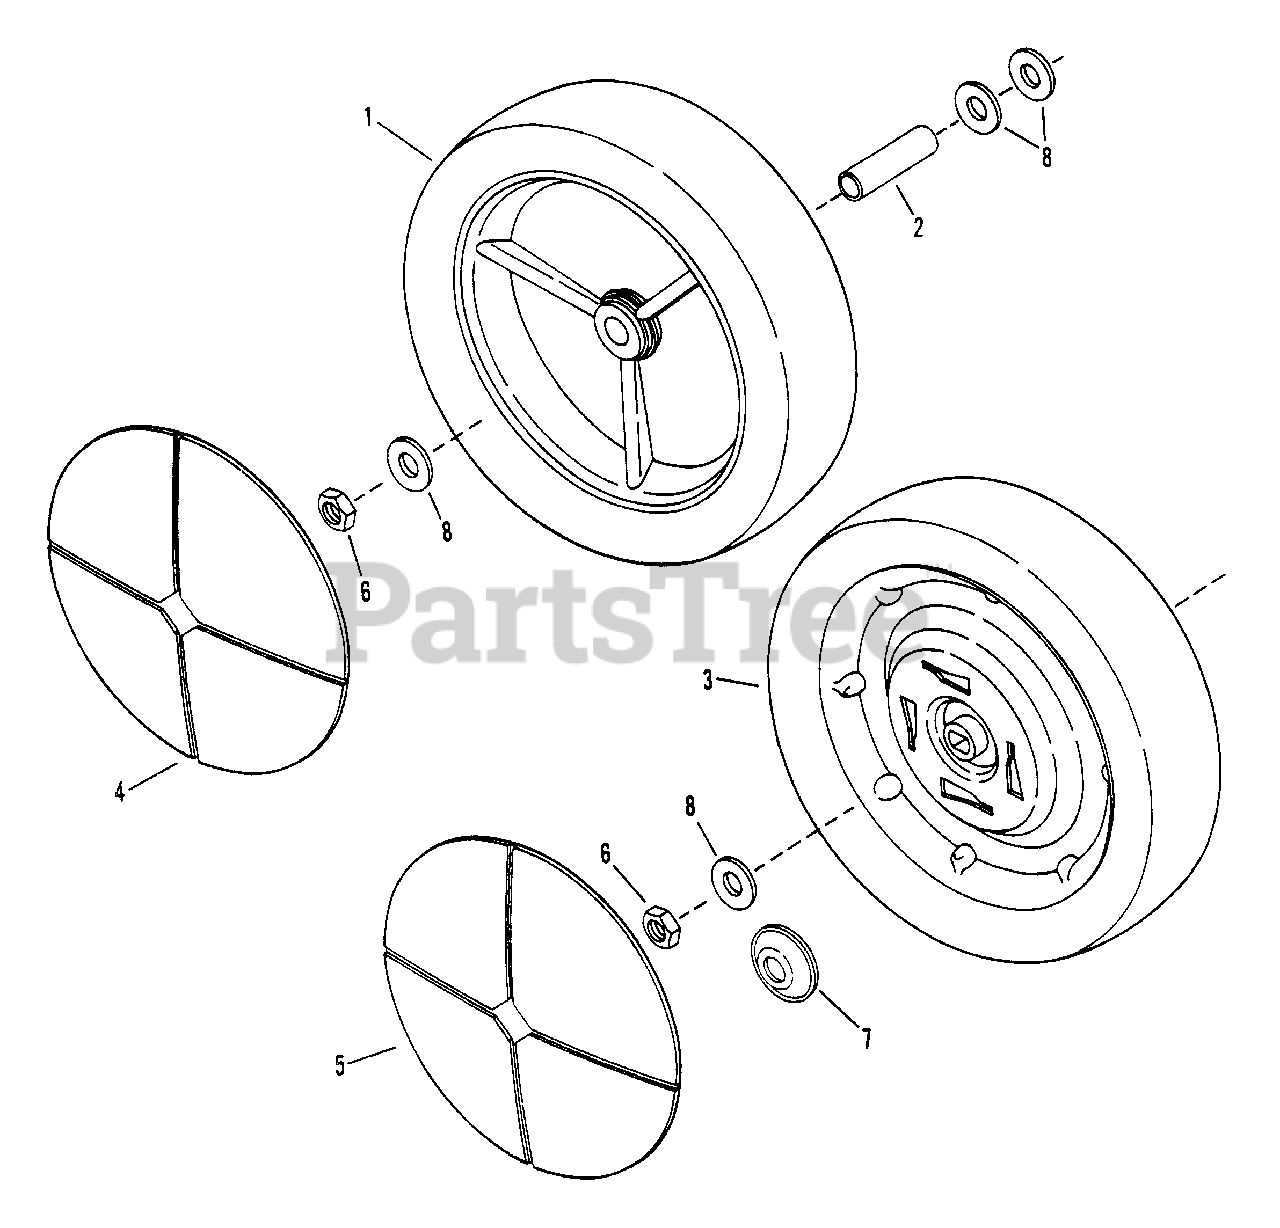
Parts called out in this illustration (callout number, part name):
1	WHEEL,9 x 2.00 Plastic Rim
2	WHEEL, 9 x 2.00 Plastic Rim
2	BUSHING, Axle
3	WHEEL, 9 x 2.00 Steel Rim
4	COVER, Wheel
5	COVER, Wheel
6	NUT, 5/16-18 Hex Center Lock
7	CAP, Deep-Dish Hub
8	WASHER, 7/16 Flat
